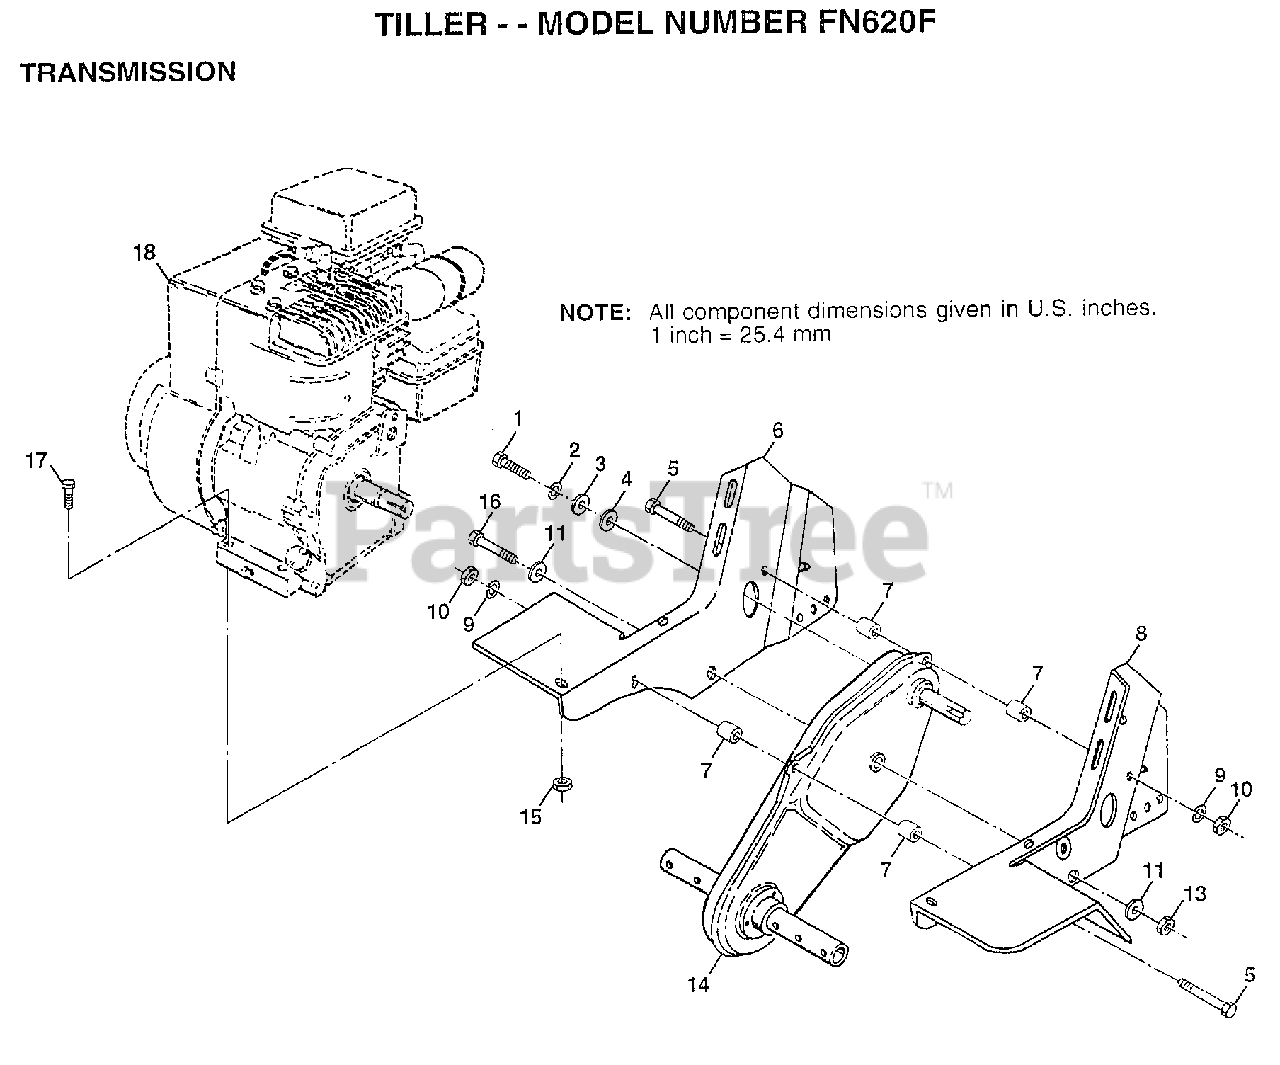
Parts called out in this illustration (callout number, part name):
1	BOLT
2	LOCKWASHER
3	WASHER
4	WASHER
6	ENGINE BRKT RH
7	SPLIT SPACER RT
8	ENGINE BRKT LH
9	LOCKWASHER
10	NUT.HEX.5/16-18
11	WASHER
13	NUT
16	BOLT HEX 3/8-16
17	BOLT.HEX.5/16-1.5
